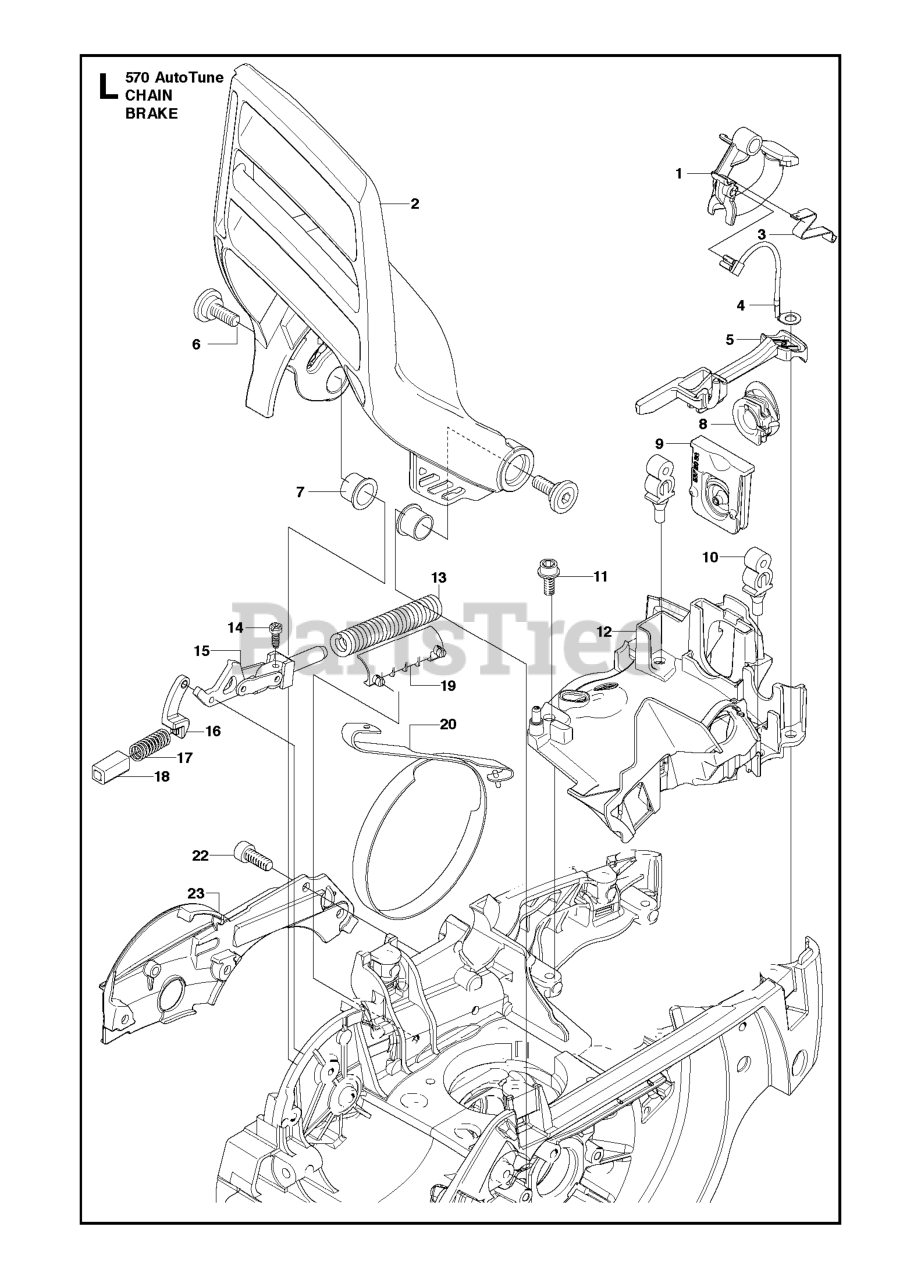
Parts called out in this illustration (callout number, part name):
2	CHAIN BRAKE
5	CHOKE CONTROL
11	SCREW
13	BRAKE SPRING
15	KNEE JOINT
17	LOCK SPRING
19	%SUPPORT
20	BRAKE BAND
